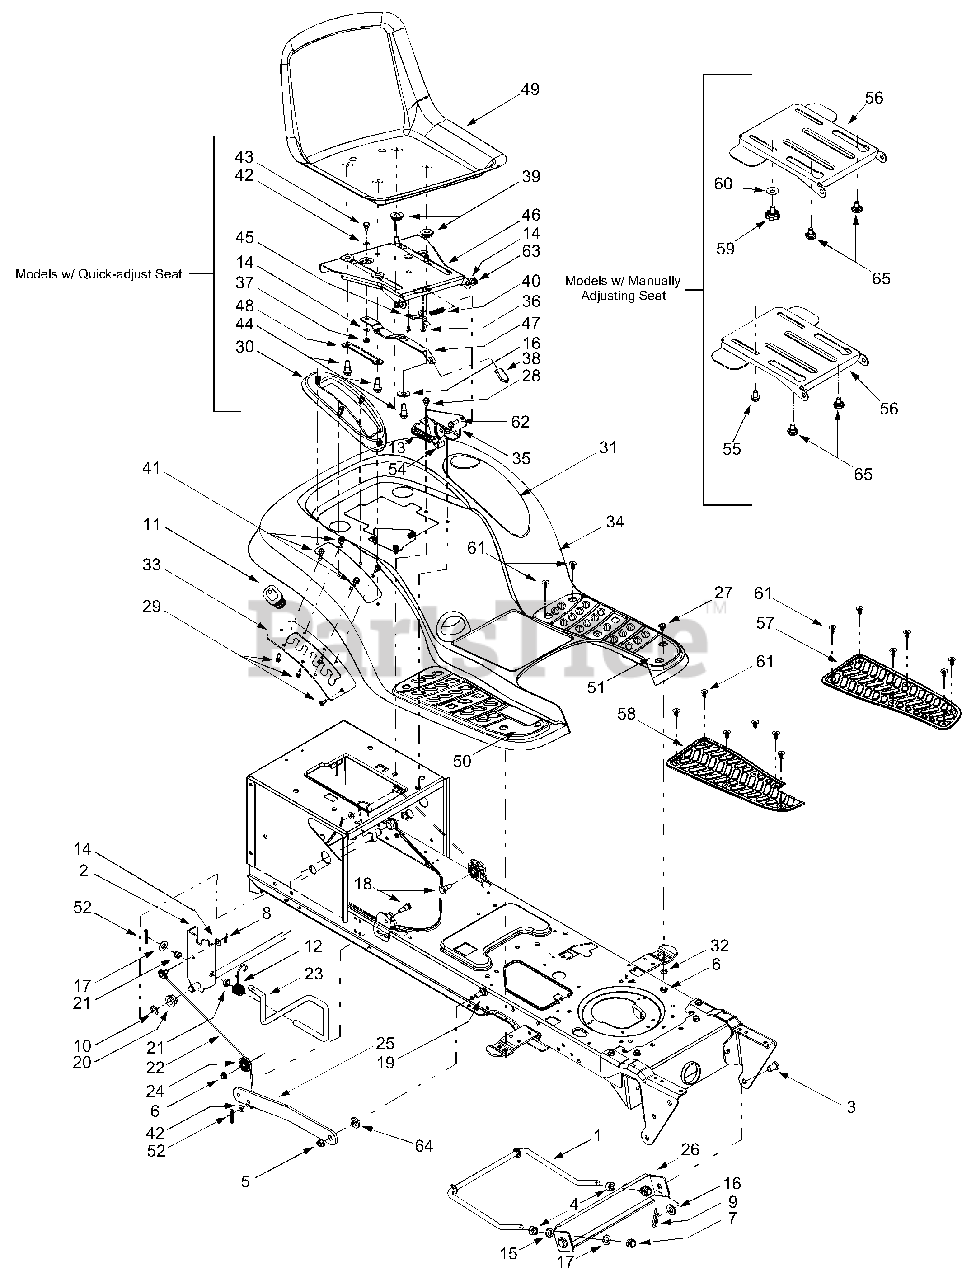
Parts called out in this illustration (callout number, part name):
1	Deck Stabilizer Rod
3	Clevis Pin,.5 x.78
4	Hex Nut, 1/2-13
5	Flange Lock Nut, 3/8-16
6	Flange Lock Nut, 5/16-18
7	Hex Nut, 1/2-13
8	Internal Cotter Pin
9	Internal Cotter Pin
10	E-ring
11	Handle Grip
12	Torsion Spring
13	Extension Spring,.84 x 4.6
14	Flat Washer, 5/16
15	Lock Washer, 1/2
16	Flat Washer,.31 x 1.062 x.134
17	Flat Washer,.51 x 1.12 x.06
18	Hex Cap Screw, 5/16-18 x.62
19	Shoulder Screw, 3/8-16
20	Hex Flange Bearing
21	Snap Flange Bearing
22	Lift Cable, 16.16
23	Lift Handle
24	Roller Pulley
27	Carriage Bolt, 5/16 x.62
28	Self-tapping Screw, 5/16-18 x.625
29	Self-tapping Screw, 1/4-15 x.75
30	Lift Lever Cover
31	Cover w/ Cup Holder
32	Flat Washer,.349 x 1.0 x.063
36	Screw, #10-16 x.375
37	Hex Flange Lock Nut, 1/4-20
38	Seat Adjuster Grip
39	Spacer
40	Compression Spring,.41 x 1.5
41	Self-tapping Screw, 5/16-18 x.625
42	Flat Washer,.344 x.62 x.03
43	Shoulder Screw,.340 x.285,1/4-20
44	Shoulder Screw,.50 x.50, 3/8-16
45	Seat Stop
48	Seat Adjustment Selector
49	High Back Seat
50	RH Foot Pad, Rubber
51	LH Foot Pad, Rubber
52	Cotter Pin
54	Seat Lift Bracket
55	Hex Head Washer Screw, 3/8-16 x.625
57	RH Foot Pad, Rubber
58	LH Foot Pad, Rubber
59	Knob, 3/8-16
60	Cupped Washer,.39 x 1.12
61	Ratchet Clip
62	Shoulder Screw,.437 x.286
63	Speed Nut,.3125
64	Flat Washer,.531 x.93
65	Shoulder Screw
